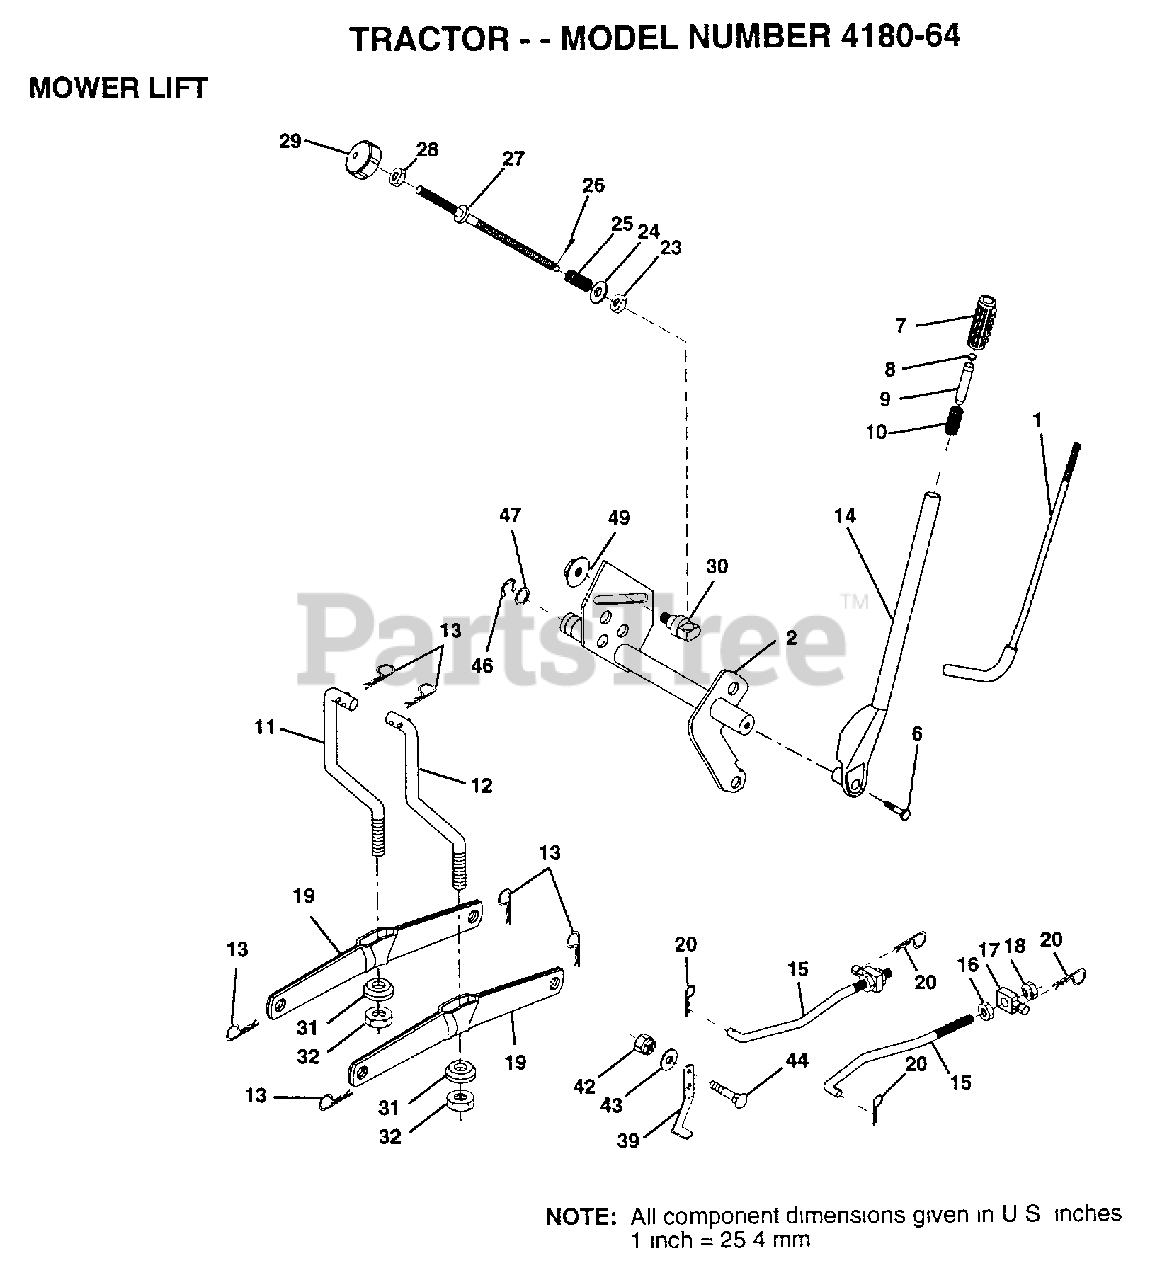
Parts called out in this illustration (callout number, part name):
1	LEVER ROD LT
2	SHAFT LIFT W/IND
6	"BOLT,HEX"
7	GRIP
10	SPRING T
11	LINK.LIFT.LH.GTV
12	LINK.LIFT.RH.GTV.
15	LINK.FRONT
16	NUT
17	TRUNION
18	NUT.LK.W/WSH.1/2.
19	ARM SUSP REAR
20	RETAINER.SPRING
23	NUT T
24	WASHER
25	SPRING.COMP.INF.H
27	ROD.ADJ.LIFT
28	NUT
29	KNOB INF 3/8-16
30	TRUNNION
31	BEARING PVT LH
32	NUT.CROWNLOCK.3/8
39	STOP.OVER.CENTER
43	WASHER GT
44	BOLT
46	E-RING
47	WASHER
49	NUT.HXFLG.LOCK.
